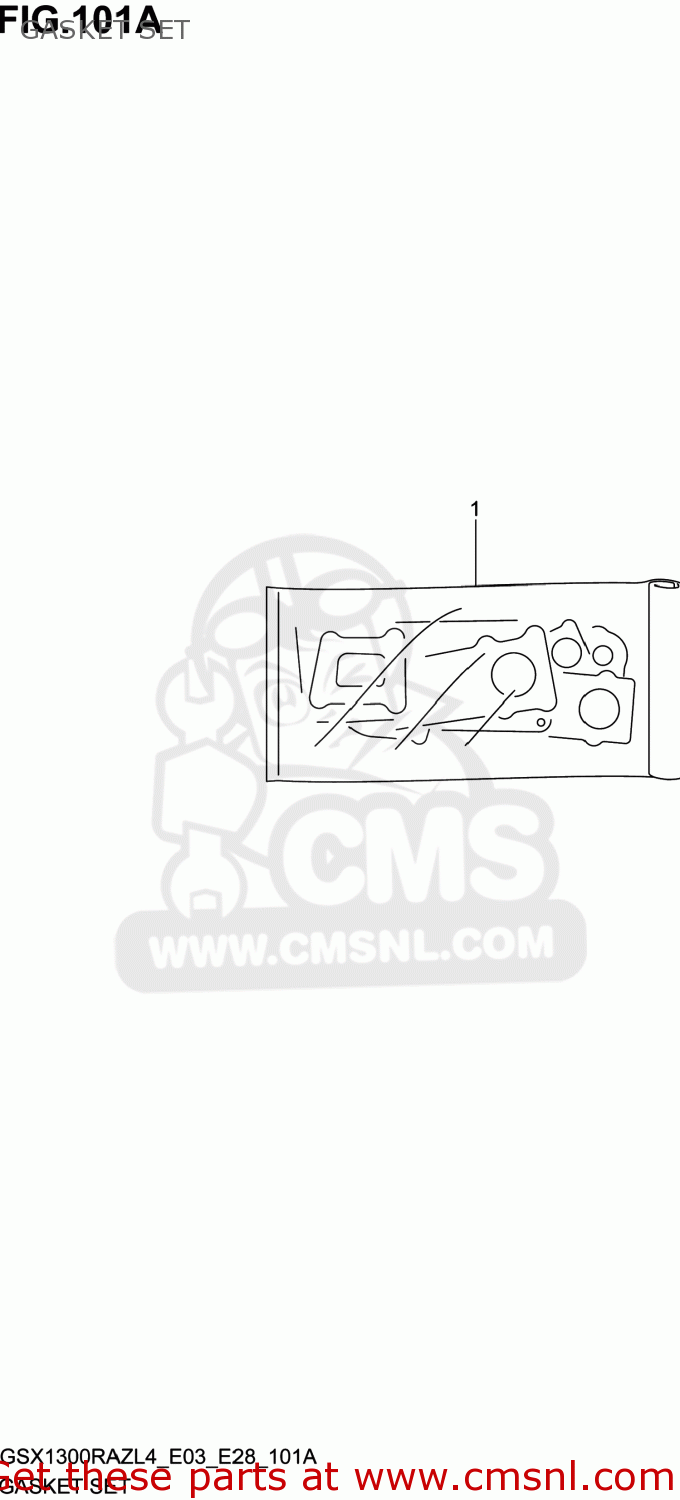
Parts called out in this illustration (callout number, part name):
1	GASKET SET (NAS)
2	GASKET,CYLINDER HEAD (NAS)
3	GASKET,CYL HEAD COVER NO.1 (NAS)
4	GASKET,CYL HEAD COVER NO.2 (NAS)
5	GASKET,CYLINDER (NAS)
6	GASKET,CL COVER (NAS)
7	GASKET,MAGNETO COVER (NAS)
8	GASKET,GEAR SHIFT COVER (NAS)
9	GASKET,OIL PAN(ASB) (NAS)
10	GASKET,STARTER CLUTCH COVER (NAS)
11	GASKET,START IDLE GEAR CAP (NAS)
12	GASKET,TENSIONER ADJUSTER (NAS)
13	GASKET,EXHAUST PIPE (NAS)
14	WASHER,CYL HEAD COVER
